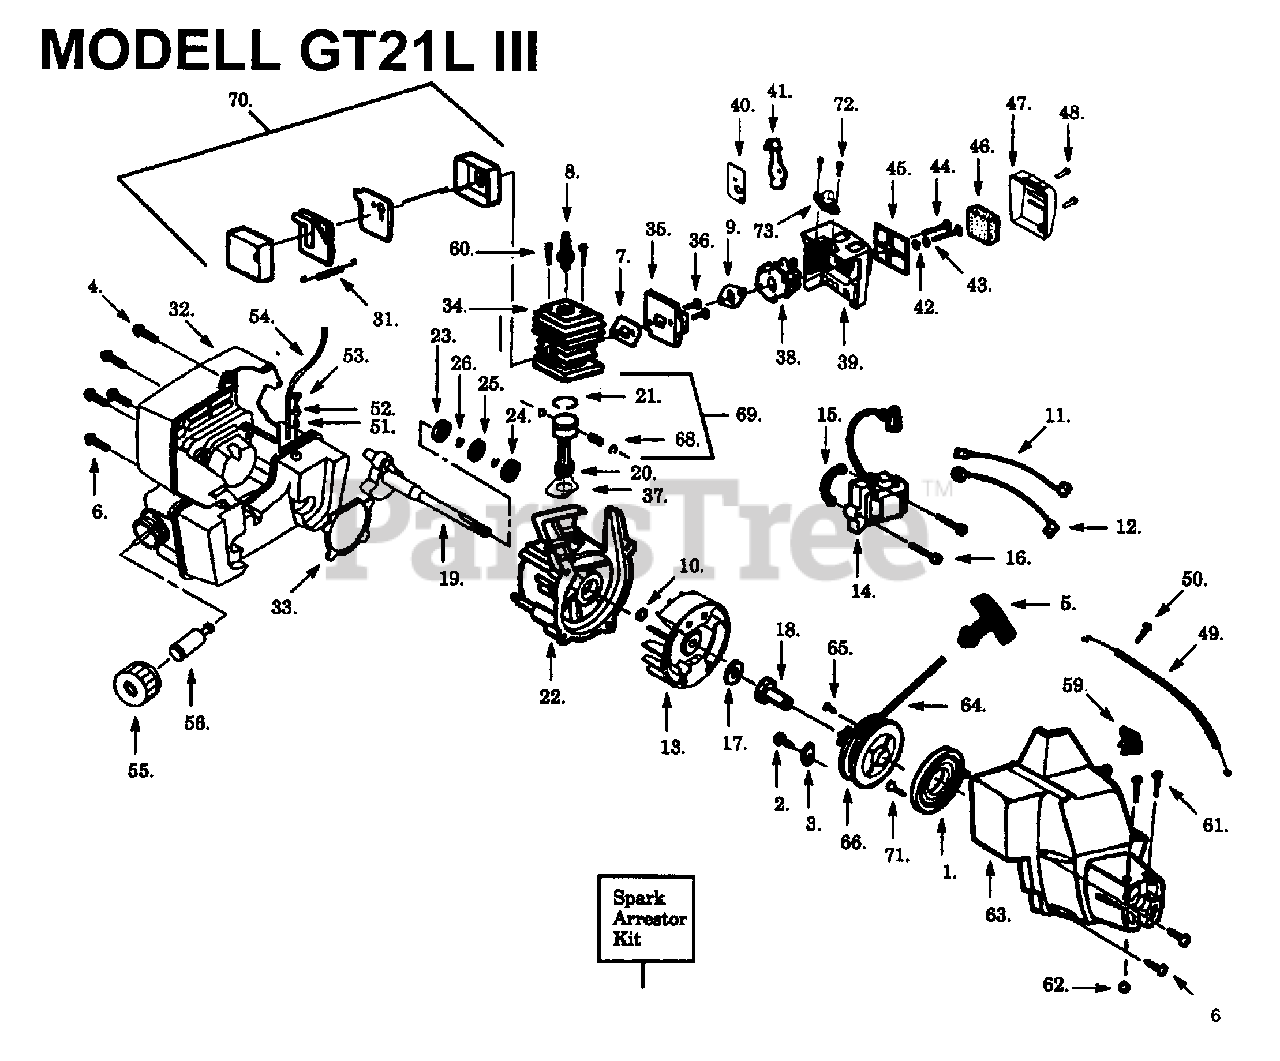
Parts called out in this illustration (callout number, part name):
1	SPRING-STARTER
2	SCREW 8-16 X 9/16 (PLAS
5	HANDLE-STARTER
6	SCREW - SHROUD
7	GASKET
8	SPARK PLUG CJ8 NLA
9	GASKET
10	RETAINING RING
11	LEAD WIRE
12	GROUND WIRE
13	FLYWHEEL
14	IGNITION MODULE
15	SPACER - IGNITION MODULE
17	WASHER FLAT
18	COUPLING-DRIVE
19	CRANKSHAFT ASSEMBLY
20	CONNECTING ROD
21	PISTON RING
22	CRANKCASE ASSY
23	BEARING
25	SEALING RING
31	MUFFLER SPRING
33	GASKET, CRANKCASE
36	SCREW - CARB. ADAPTOR
37	REPL BY 530 01 92-23
38	REPL BY 530 06 96-47
40	CHOKE PLATE
41	CHOKE FLAP
43	CHOKE SPACER
45	FILTER PLATE
46	AIR FILTER FOAM
47	AIR FILTER COVER
48	SCREW - THROTTLE HOUSING
49	THROTTLE CABLE
51	VALVE-CHECK (DUCKBILL)
55	REPL BY 530 01 43-47
56	FUEL PICK UP ASSY
59	REPL BY 530 06 95-72
61	SCREW - PINCH CLAMP
62	LOCKNUT-HEX 10-24
63	REPL BY 530 04 74-91
65	SCREW-6-19X9/32 PAN/SEM
66	STARTER PULLEY KIT
67	KIT-SPARK ARRESTOR (OLD STYLE)
68	WRIST PIN RET.
69	PISTON
70	MUFFLER KIT
73	PRIMER BULB ASSEMBLY
